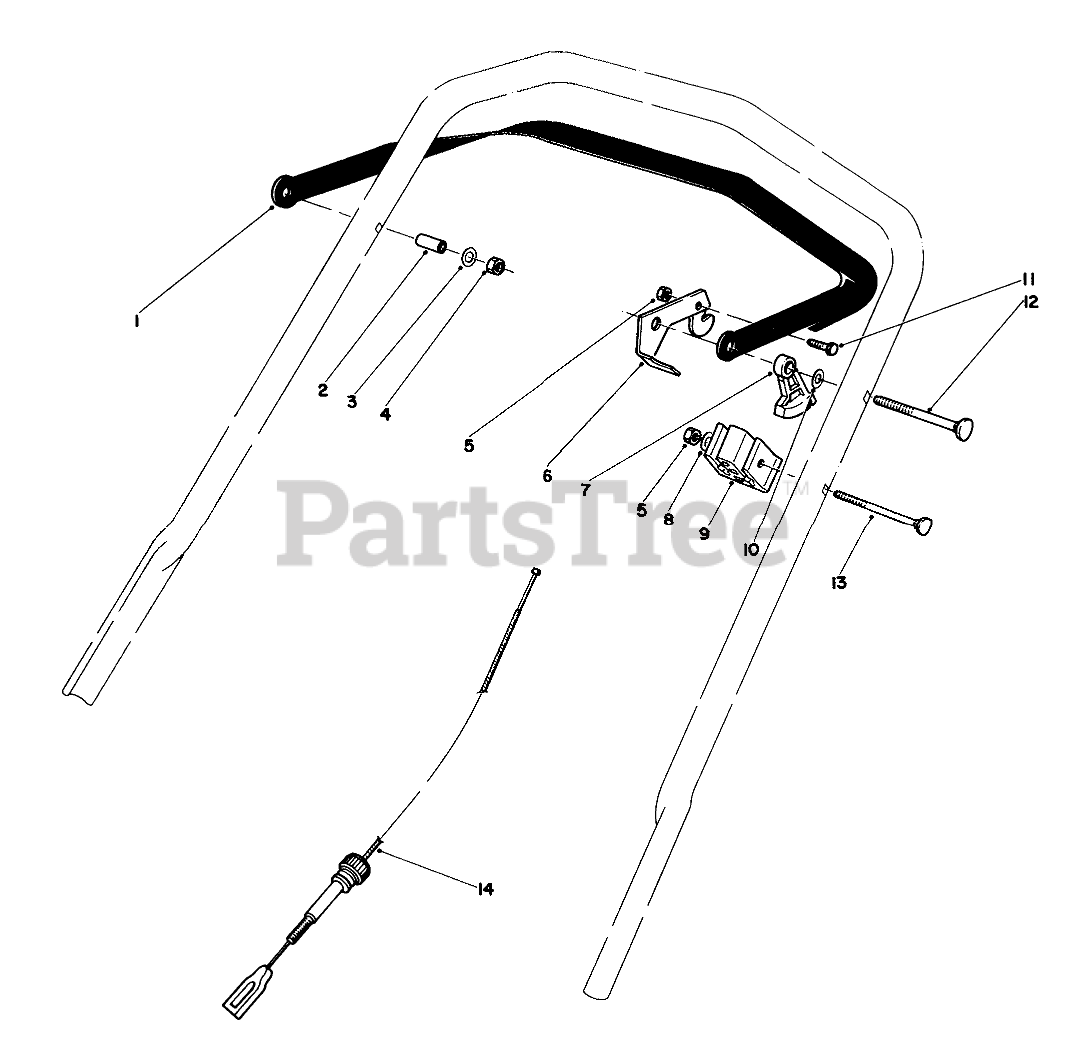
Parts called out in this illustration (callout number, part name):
1	Bar-Control
2	Spacer
3	WASHER-FLAT
4	NUT-LOCK, NI
5	NUT-LOCK, NI
6	CONTROL LEVER
7	LEVER-TRACTION
8	WASHER-FLAT
9	SUPPORT-CABLE
10	WASHER-FLAT
11	SCREW-HH
12	5/16-18 X 2 HNDLE SCREW
13	SCREW-HANDLE
14	CABLE-TRACTION
